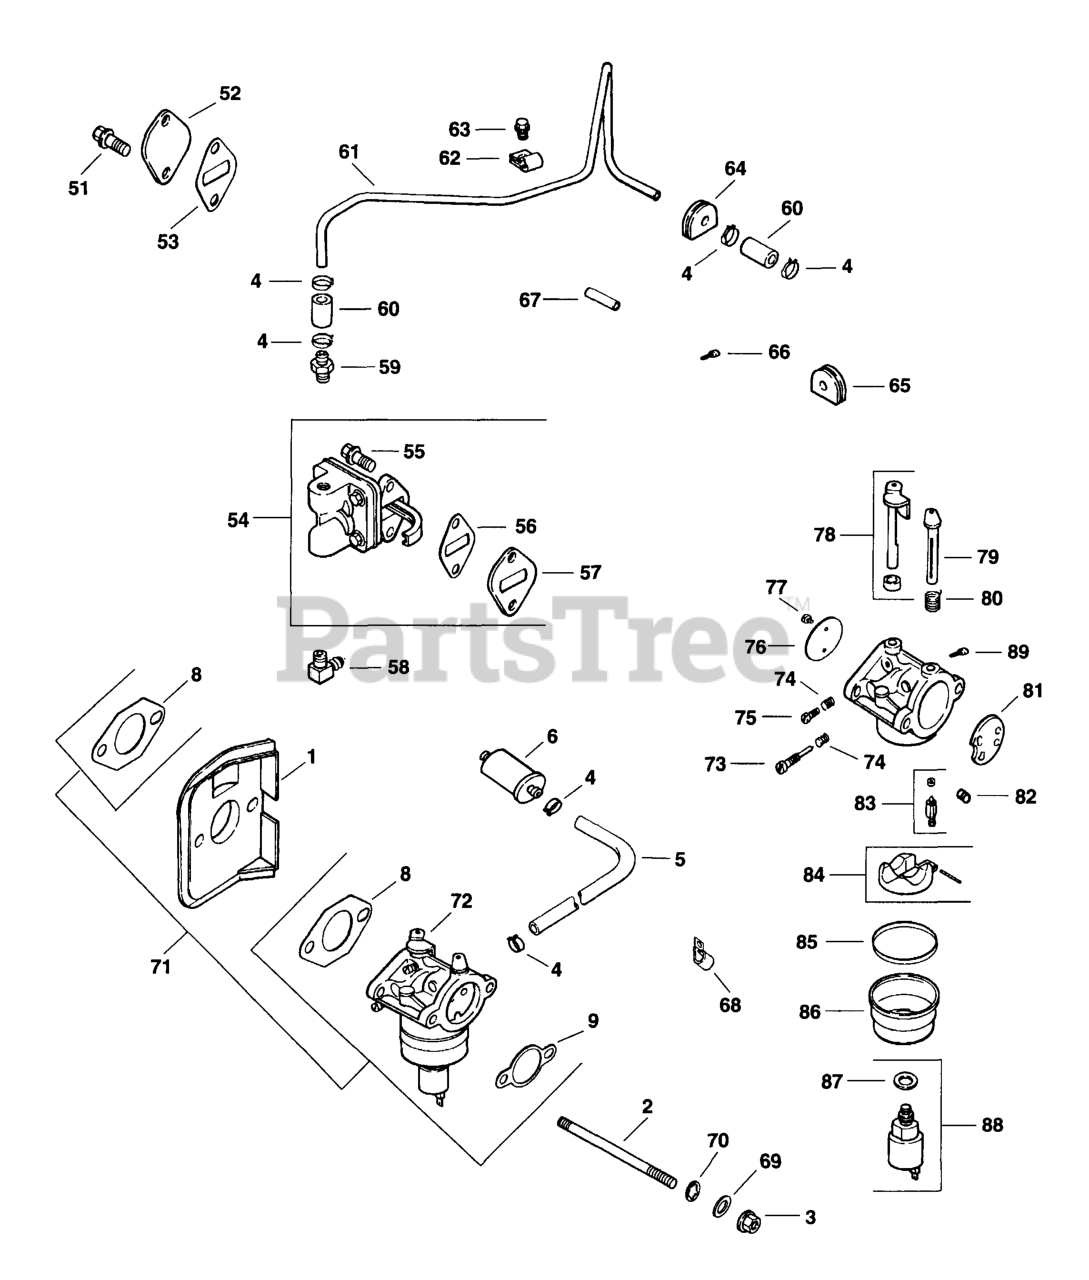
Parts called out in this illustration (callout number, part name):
1	Deflector, Heat
2	Stud, Carburetor M6x1.0x122.8
3	Nut, Hex. Flange M6x1.0
8	Gasket, Carburetor
9	Gasket, Air Filter
